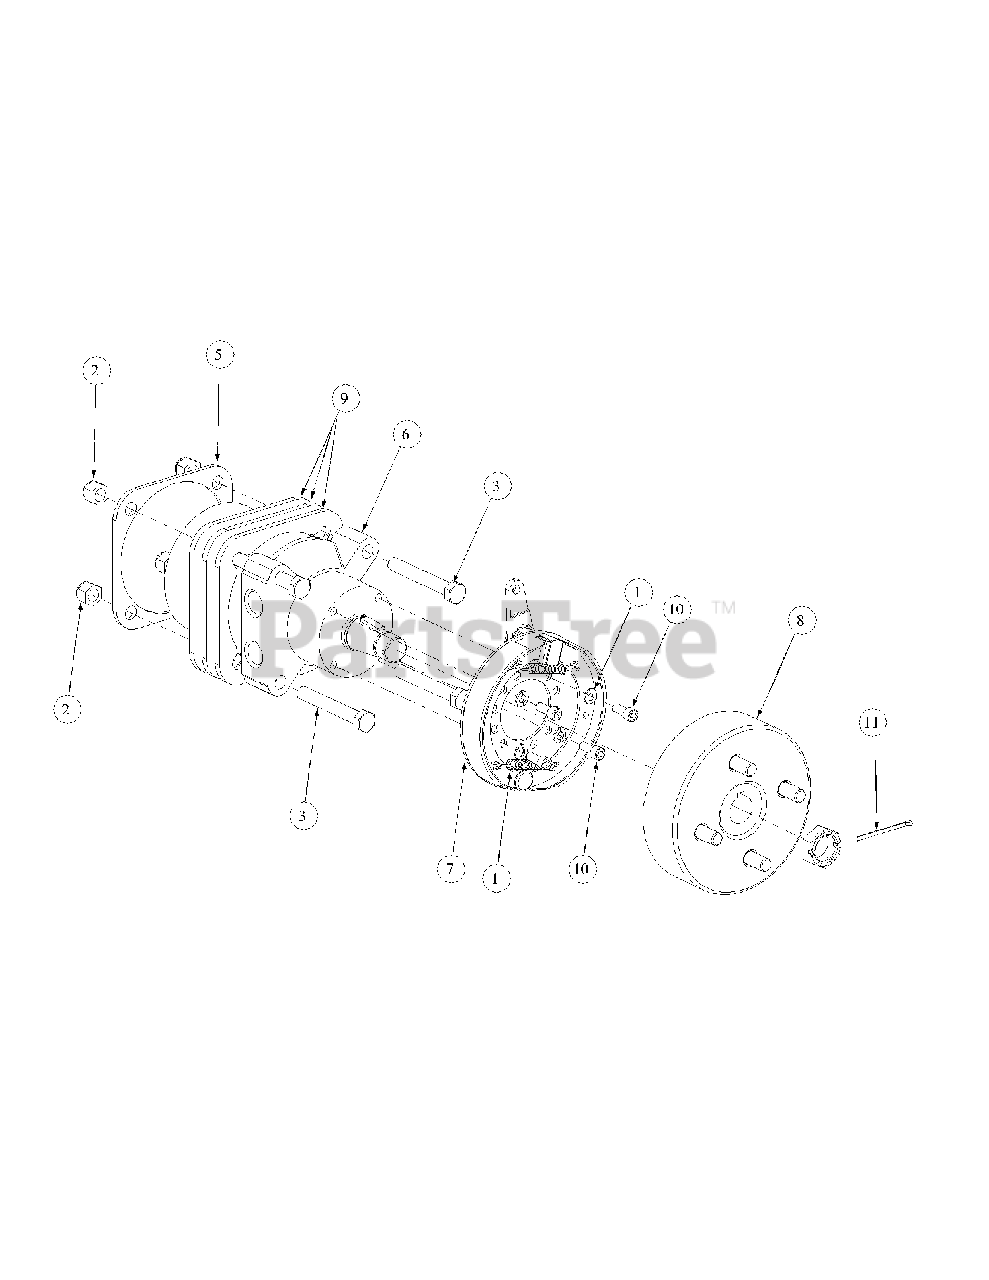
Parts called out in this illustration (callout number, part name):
1	Lock Washer, 5/16
2	Lock Nut, Nylon Insert, 1/2-13
3	Capscrew, 1/2-13 x 3.5
4	Hyd. Motor, Left Hand:
5	Motor Plate
6	Hydro Motor, Right Hand
7	Brake Assembly w/Line
8	Hub and Drum Assembly w/Studs
9	Motor Spacer
10	Capscrew w/Socket, 5/16-18 x 3/4
11	Cotter Pin 5/32 x 1-1/2
